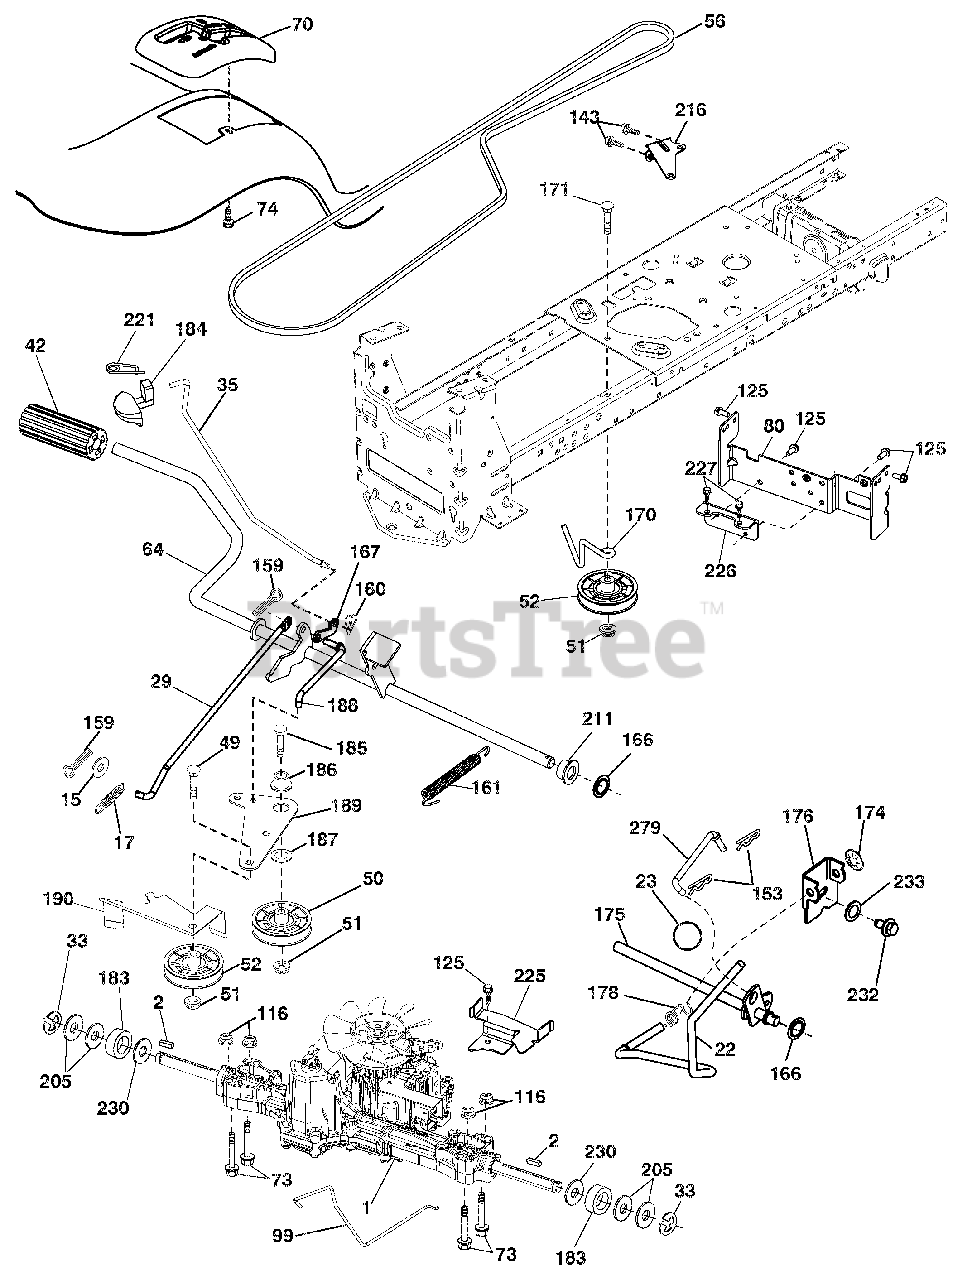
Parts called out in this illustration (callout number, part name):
1	TRANSAXLE, TUFFTORQ K46BA (448348) (ORDER PARTS FROM TRANSAXLE MANUFACTURER.)
2	KEY.SQUARE.2.0 X .1845/.1865
15	WASHER.13/32 X 13/16 X 16 GA.
17	SPRING.BRAKE.K46.GREEN
22	ROD.SHIFT.FENDER.TLT.2006
29	ROD.BRAKE.K46
33	E-RING.#5133-75
35	ROD, BRAKE, PARK
42	COVER PEDAL BLK ROUND
49	BOLT.RDHD.3/8-16UNCX1-3/4.GR5
50	IDLER.FLAT.910"OFFSET
51	Nut, Hex, Flangelock 3/8-16
52	IDLER.V-GROOVE.910"OFFSET
56	V-BELT.MOWER.92.40.42/K46
64	SHAFT ASM.PEDAL.BRAKE CONTROL
70	CONSOLE SHIFT STL HYD BLACK TX
73	BOLT 5/16-18 X 2 1/2 G.5
74	SCREW.HEX.WSH.HI-LO.1/4X1/2UNC
80	STRAP.TORQUE.K46/18"TEX
99	ROD.SPRING.BYPASS.K46.LT.Z
116	Nut, Lock Hex Flange 5/16-18 u
125	SCREW.5/16-18X3/4.SMGML.TAP/BL
143	SCREW.THDROL.5/16-18 X 1/2TYTT
153	RETAINER SPRING
159	PIN.COTTER.1/8 X 3/4.CAD.
160	RETAINER.CLIP(M).DIA.290
161	SPRING.RETURN.CLUTCH.6.75
166	NUT PUSH .625
167	LATCH.BRAKE.PARKING
170	KEEPER BELT CENTERSPAN
171	BOLT.RD.HD.SQ.NK.3/8-16UNC X 2
174	NUT.PUSH..500
175	SHAFT ARM SHIFT
176	ARM.CLEVIS.ROD.SHIFT
178	SPRING.SHIFT.GT.2006
183	SPACER.AXLE.HYDRO/PEERLES
184	HANDLE PARKING BRAKE
185	BOLT.RDHD.3/8-16UNC X2-3/4 GR5
186	SPACER.RETAINER
187	WASHER.13/32 X 2 X 10 GA.
188	LINK.CLUTCH.GROUND DRIVE
189	BELLCRANK.GROUNDRIVE.NSTG/NSTL
190	KEEPER.BELLCRANK.DRIVE.GROUND
205	WASHER.25/32 X 1-5/8 X 16GA.
211	BUSHING.SHAFT.BRAKE.HAND CONTR
216	BRACKET.PULLEY.IDLER.WTEX
221	RETAINER.SPRING.CLIP.HANDLE
225	KEEPER.BELT.TRANSAXLE.K46
226	BRACKET.MOUNT.TORQUE.K46.TLT
227	SCREW 5/16-18 X 3/4
230	WASHER.HARDEN..793 X 1.637X060
232	BOLT.FIN HEX.7/16-14X1 GR5
233	WASHER.SERRATED
279	LINK SHIFT T/A
